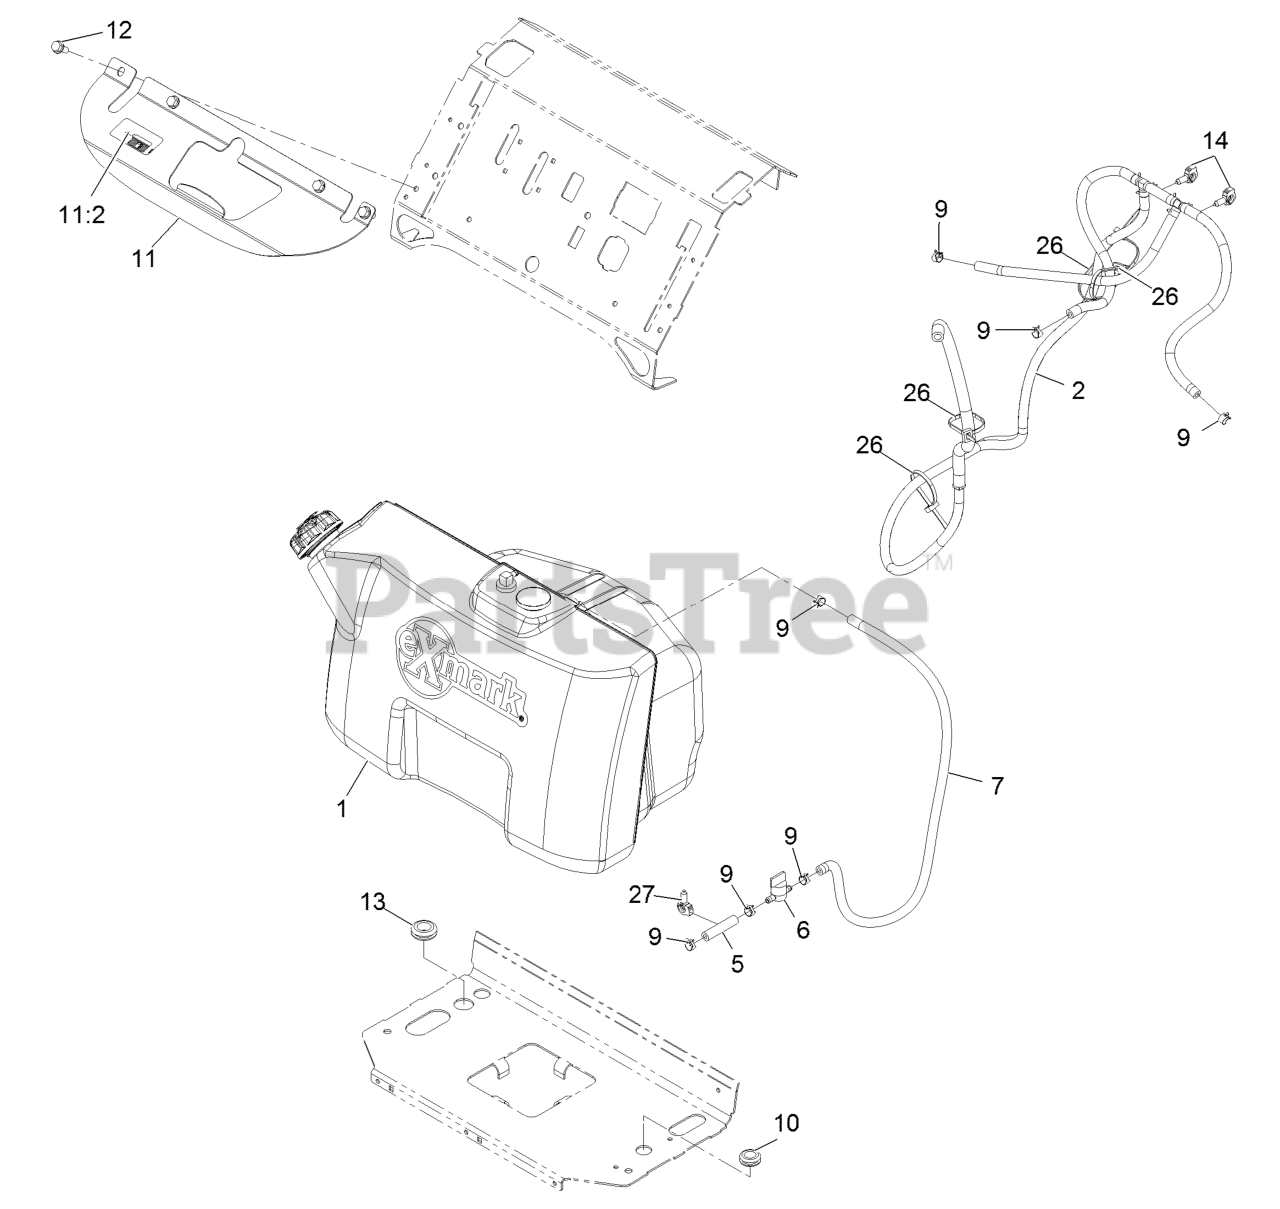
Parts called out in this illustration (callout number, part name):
2	VENT ASM
5	HOSE-FUEL
6	VALVE-FUEL
7	HOSE-FUEL
9	CLAMP-HOSE
10	GROMMET
11	BRACKET-TANK
11:2	DECAL-FILL, FUEL
12	SCREW-THD ROLL, HWH
13	GROMMET
14	CLIP-HARNESS
26	TIE-CABLE
27	CLIP-HARNESS
